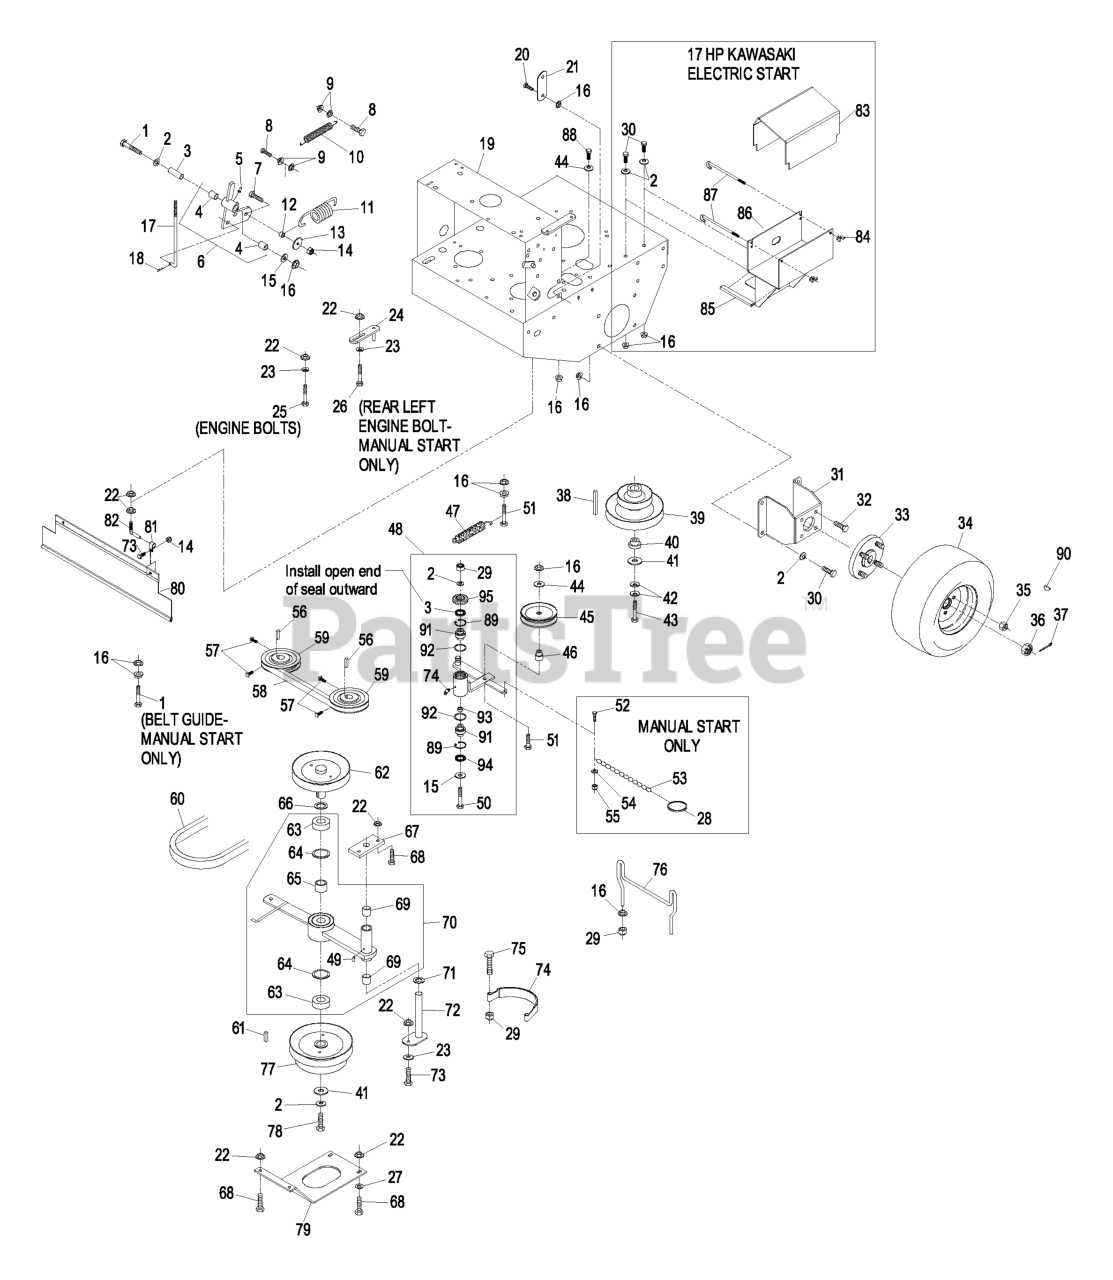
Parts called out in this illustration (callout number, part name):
1	SCREW-HH
2	WASHER-BELLEVILLE
3	SEAL-LIP, SINGLE
4	SLEEVE-BEARING
5	FITTING-GREASE
6	ASM,PIVOT W/BUSHINGS
7	SCREW-HH
8	SCREW-HH
10	SPRING,EXTENSION
11	SPRING,EXTENSION
12	SPACER,CLUTCH ANCHOR
14	NUT-LOCK, NI
15	WASHER-FLAT
16	NUT-HHF, WHIZ
17	LINKAGE,LOWER
18	PIN-COTTER
19	KIT,TTHP ENG DECK
20	SCREW-HH
21	ARM-LIFT, DECK
23	WASHER-SPRING
24	GUIDE-BELT
25	SCREW-HH
26	SCREW-HH
27	WASHER-FLAT
28	RING-SPLIT
29	NUT-LOCK, NI
30	SCREW-HH
31	WLD,MOTOR MOUNT 36
32	SCREW-HHF
34	WHEEL AND TIRE ASM
35	NUT-LUG
36	NUT-HEX, SLOTTED
37	PIN-COTTER
38	KEY,MACH 1/4X1/4X2-5/8
39	SHEAVE, DRIVE
40	BUSHING,CLUTCH KEEPER
42	WASHER-SPRING
43	SCREW-HH
44	WASHER-FLAT
46	BUSHING-IDLER
48	KIT,PUMP IDLER ARM TTHP
49	FITTING-GREASE
50	SCREW-HH
51	SCREW-HH
52	SCREW-HSH
53	CHAIN-LINK, TWIST
54	WASHER-FLAT
55	NUT-LOCK, NI
57	SCREW-SET
58	BELT,COG A 50.55
59	SHEAVE ASM
60	BELT,B-38.0
62	SHEAVE, W/ SHAFT
63	BEARING,CLUTCH SHAFT
64	RING-SNAP
65	SPACER,CLUTCH BEARING
66	WASHER-SPACER
67	PLATE-CLUTCH PIVOT
68	SCREW-HH
69	SLEEVE,BEARING
70	ASM,CLUTCH ARM W/BEARING
71	WASHER-SPACER
72	WLD,PIN PIVOT
73	SCREW-HH
74	BAND,BRAKE BLADE
75	SCREW-HH
76	GUIDE,BELT (PLTD)
77	SHEAVE,6.13 W/HUB
78	SCRW,CAP HH
79	PLATE-GUARD
80	SHIELD-DRAG
81	CLIP-LOOM
82	MOUNT,DRAG SHIELD
83	COVER,BATTERY W/DECAL
84	WINGNUT
85	TRIM-LOK
86	ASM,BATTERY STAND W/TRIM
87	BOLT - HOLD DOWN
88	SCREW-HH
89	RING-SNAP
90	KEY-WOODRUFF
91	BEARING-SPHERICAL
94	SEAL-LIP, DOUBLE
95	GUARD-TOP
